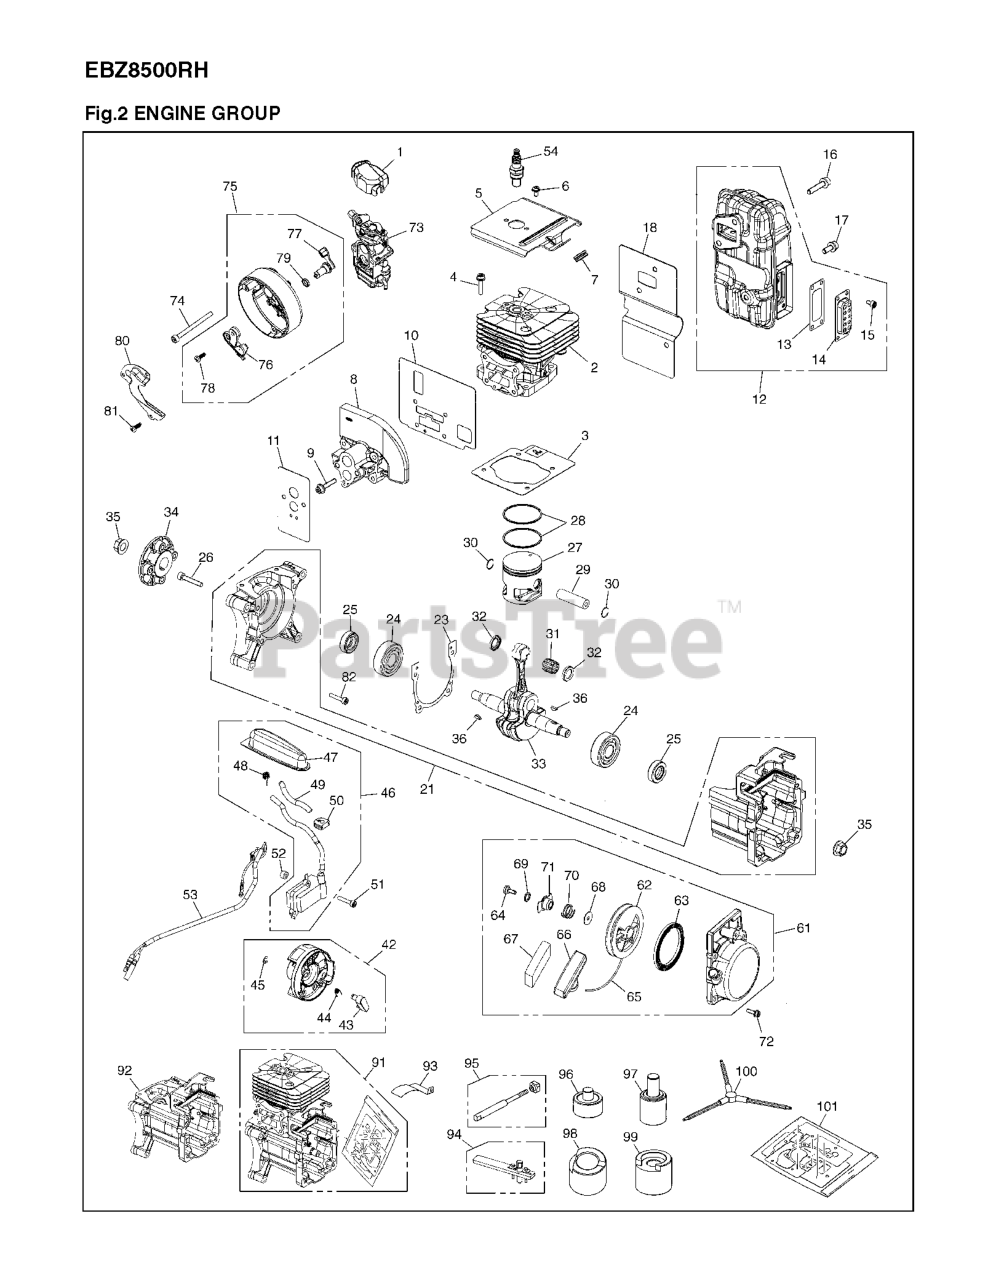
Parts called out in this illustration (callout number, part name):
2	CYLINDER ASSY
4	BOLT
8	INSULATOR
10	GASKET
12	MUFFLER ASSY
13	SPARK ARRESTER
14	DIFFUSOR
21	CRANKCASE COMP
24	BALL BEARING
25	SEAL
28	PISTON RING
29	PISTON PIN
30	SNAP RING
31	BEARING
33	CRANKSHAFT COMP
34	COUPLING
36	KEY
42	ROTOR ASSY
46	COIL ASSY
48	SPRING PLUG
50	GROMMET
51	BOLT TORX
52	SPACER
54	PLUG CMR7H
61	RECOIL ASSY
66	KNOB
67	COVER
68	WASHER
70	SPRING FRICTION
71	PLATE
73	CARBURETOR
75	CUP ASSY
76	PLATE CHOKE
78	SCREW
80	PLATE
81	SCREW
91	SHORT BLOCK
92	CRANKCASE ASSY
93	GAUGE
94	PULLER ASSY
95	ROD ASSY
96	BEARING GUIDE
97	OILSEAL GUIDE
98	SUPPORT CRANKCASE -S
99	SUPPORT CRANKCASE - F
100	WRENCH (RPLS 267096410)
101	GASKET KIT
